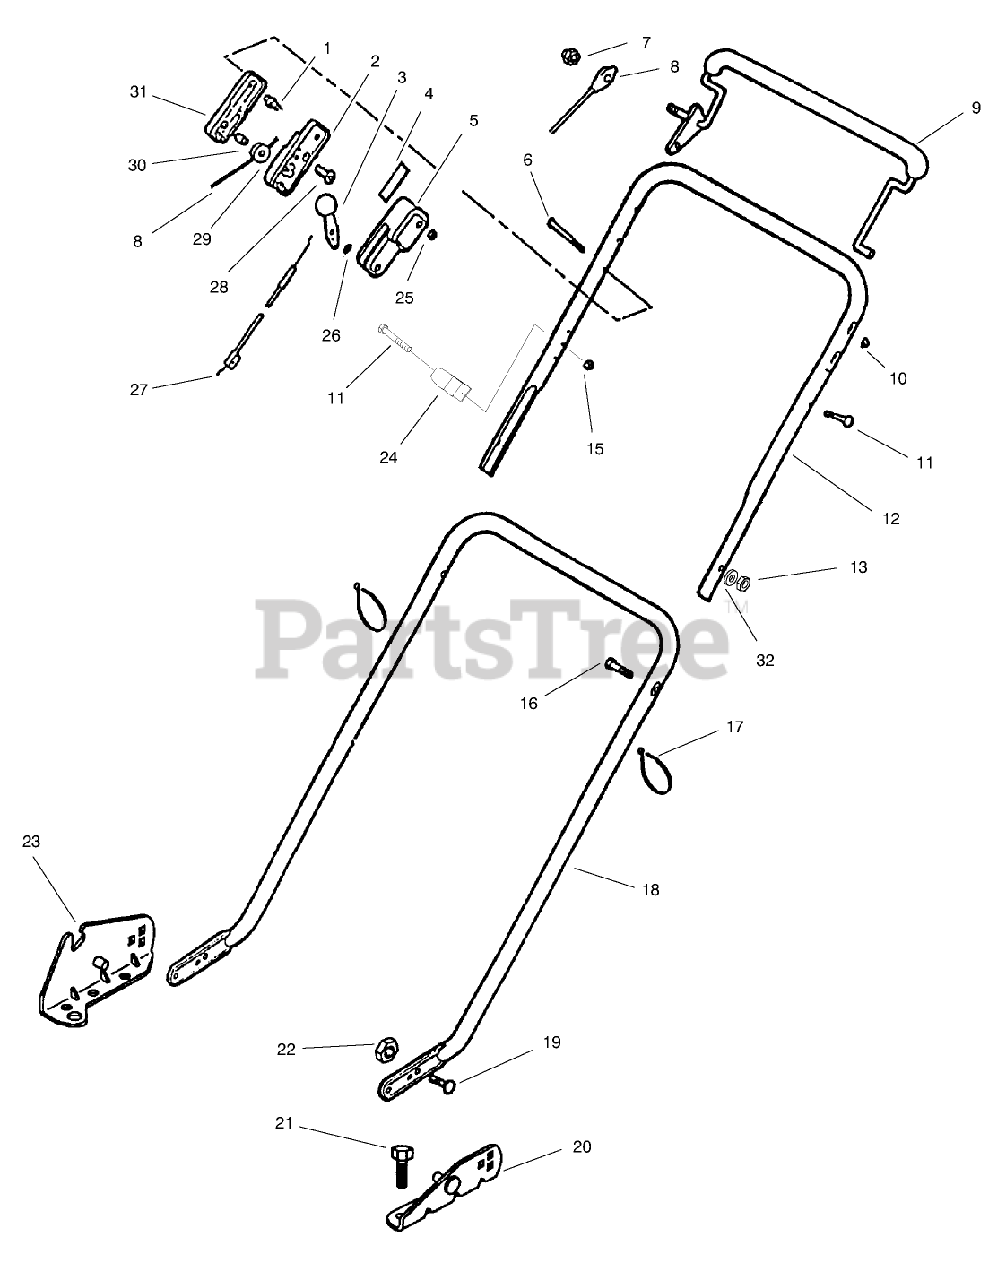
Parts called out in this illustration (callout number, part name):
1	COLUMN
2	CENTER CONTROL CASE
3	ASM - LEVER & KNOB
4	DECAL - THROTTLE CONTROL
5	INNER CONTROL CASE
6	SCREW
7	NUT ACORN
8	CABLE - CONTROL
9	CONTROL LEVER ARG
10	NUT-PUSH
11	SCREW-HH
12	HANDLE SECTION-TOP
13	NUT-LOCK, NI
15	NUT-LOCK, NI
16	SCREW-HH
17	TIE-CABLE
18	Handle-Lower
19	BOLT-CARRIAGE
20	ASM-Bracket & Pin
21	SCREW
22	NUT-LOCK, NI
23	ASM-Bracket & Pin
24	GUIDE-ROPE
25	NUT-LOCK, NI
26	WASHER-SPRING
27	CABLE - THROTTLE
28	SCREW
29	PULLEY PL
30	PIN SKF
31	OUTER CONTROL CASE
32	WASHER-CURVED
